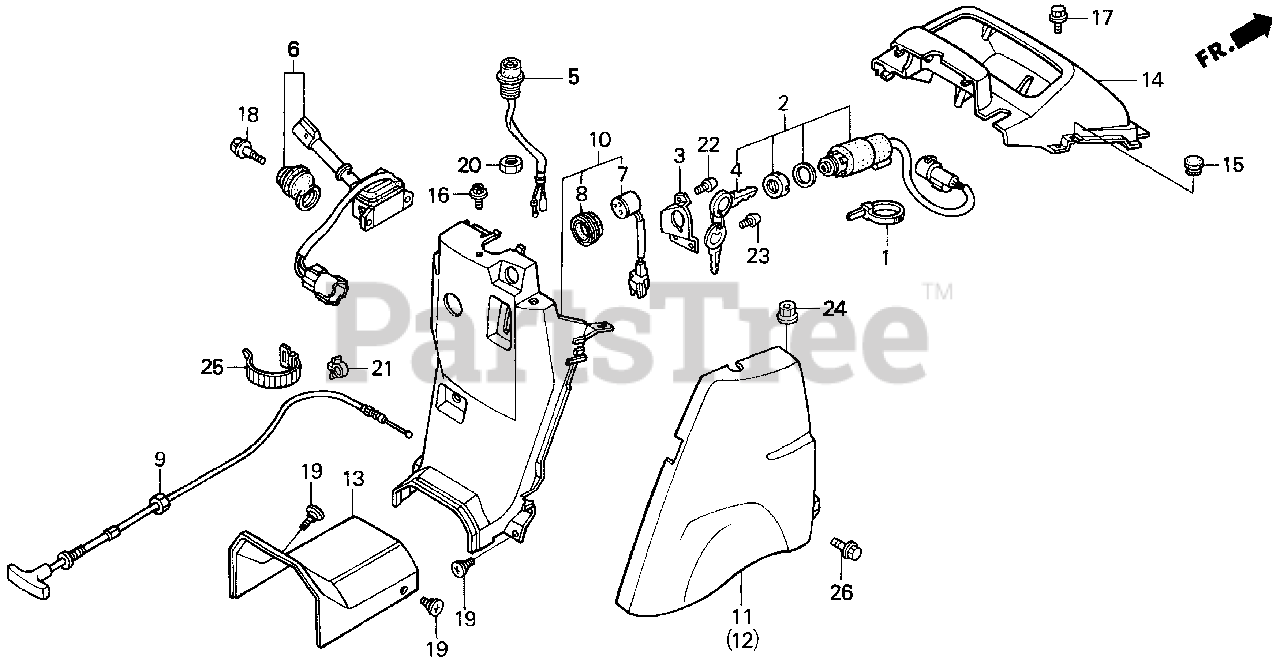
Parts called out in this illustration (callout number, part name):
1	BAND B1, CABLE
2	SWITCH ASSY., COMBINATION
3	BRACKET, COMBINATION SWITCH
4	KEY
5	SWITCH ASSY., STARTER (STATIONARY PTO SWITCH)
6	SWITCH ASSY., LIGHT COMBINATION
7	BUZZER, WARNING
8	GROMMET, PARKING BRAKE BUZZER
9	CABLE, HOOD LOCK
10	COVER ASSY., CENTER STEERING COLUMN *NH247* (ASSEMBLY GRAY)
11	COVER, R. STEERING COLUMN *R165* (JOLLY RED)
12	COVER, L. STEERING COLUMN *R165* (JOLLY RED)
13	COVER, FLOOR *NH247* (ASSEMBLY GRAY)
14	PANEL, INSTRUMENT *NH247* (ASSEMBLY GRAY)
15	GROMMET, DRAIN HOLE
16	BOLT, FLANGE (6X12)
17	BOLT, FLANGE (6MM)
18	BOLT, SETTING
19	SCREW, METER VISOR SETTING
20	NUT, HEX. (16MM)
21	CLIP, HARNESS
22	SCREW, PAN (5X6)
23	SCREW, PAN (5X12)
24	NUT, FLANGE (6MM)
25	BAND B2, CABLE HARNESS
26	BOLT, FLANGE (6X10)
